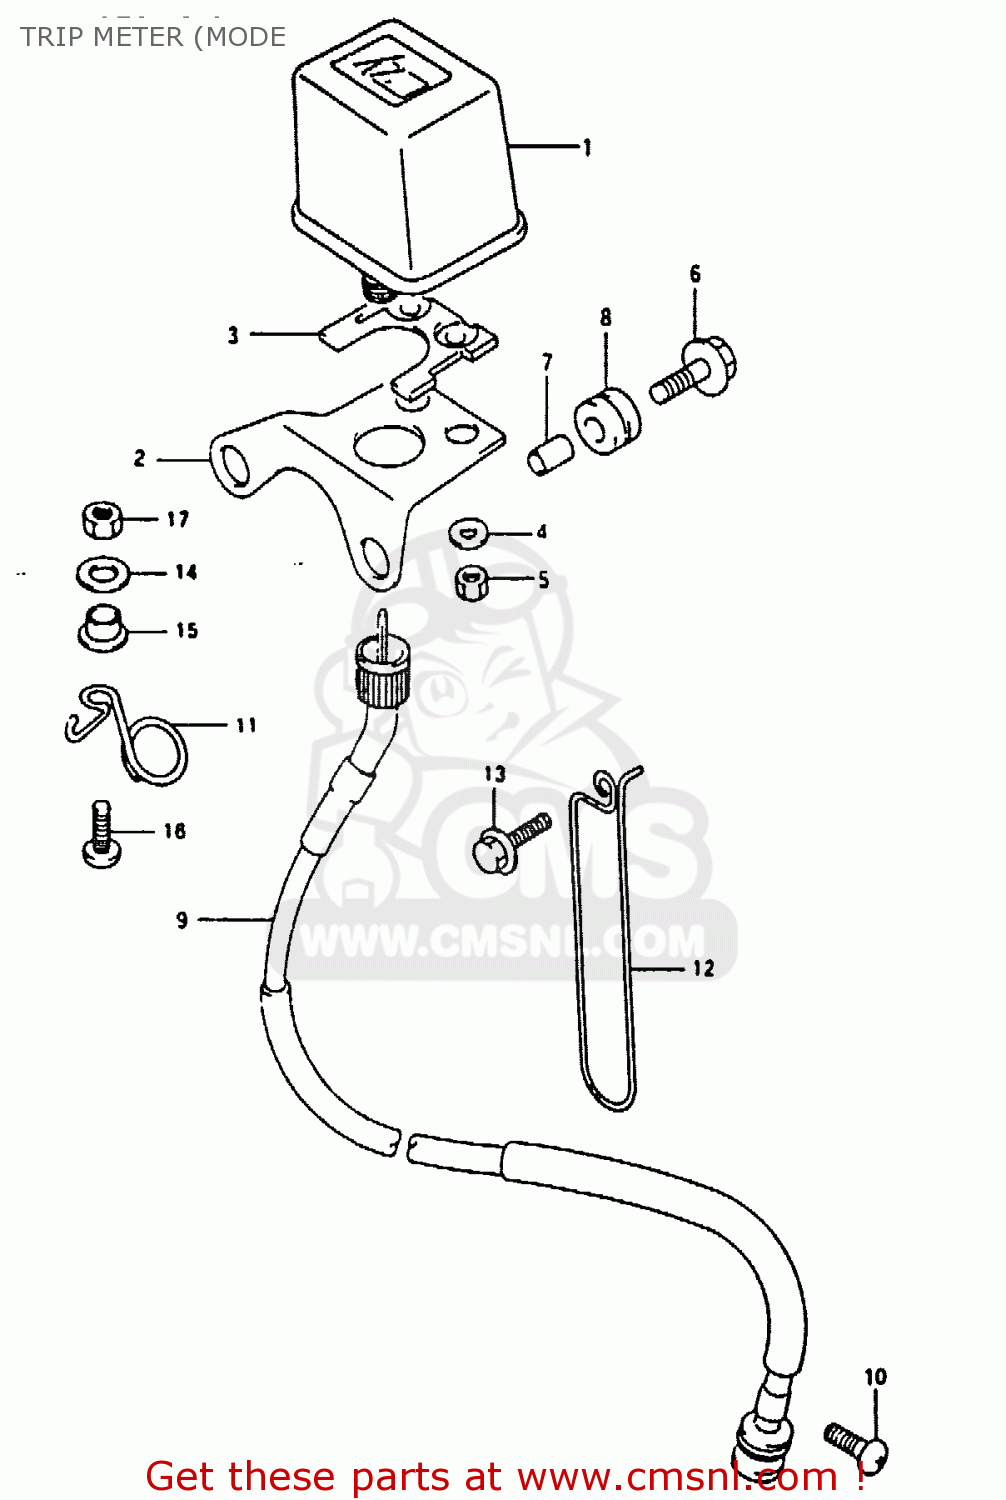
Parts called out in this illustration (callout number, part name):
1	TRIP METER
2	BRACKET
3	CUSHION
4	WASHER (4.3X13X0.80)
5	NUT
6	BOLT(6X25)
7	SPACER (6.1X8X9.5)
8	CUSHION
9	CABLE ASSY,SPEEDOMETER
10	SCREW
11	GUIDE,SPEEDOMETER CABLE
12	GUIDE,METER CABLE NO.2
13	NUT
14	WASHER
15	RIVET
16	SCREW
17	NUT 6MM
